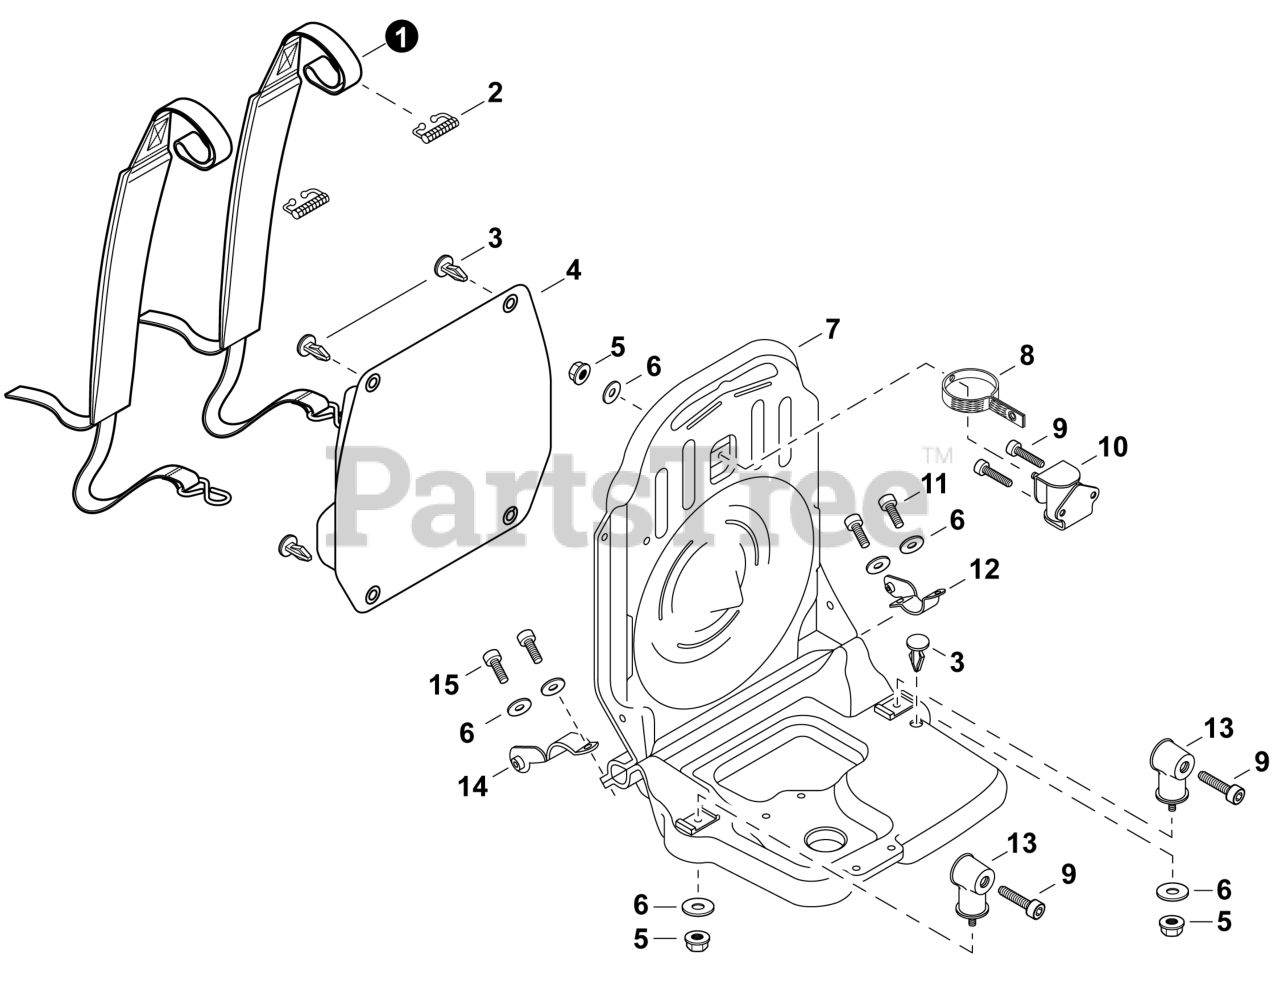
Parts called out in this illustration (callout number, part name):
1	HARNESS ASSY, BACKPACK
2	CLIP, HARNESS
4	CUSHION, BACKPACK
5	NUT, FLANGE M5
6	WASHER 5.5x16x2T
7	FRAME, BACKPACK
8	STRAP, SAFETY
9	SCREW, TAPPING 5x16
11	BOLT 5x20 HSH
12	BRACKET, HARNESS (B)
13	CUSHION, FRAME 5
14	BRACKET, HARNESS
15	BOLT, TAPPING 5x25
